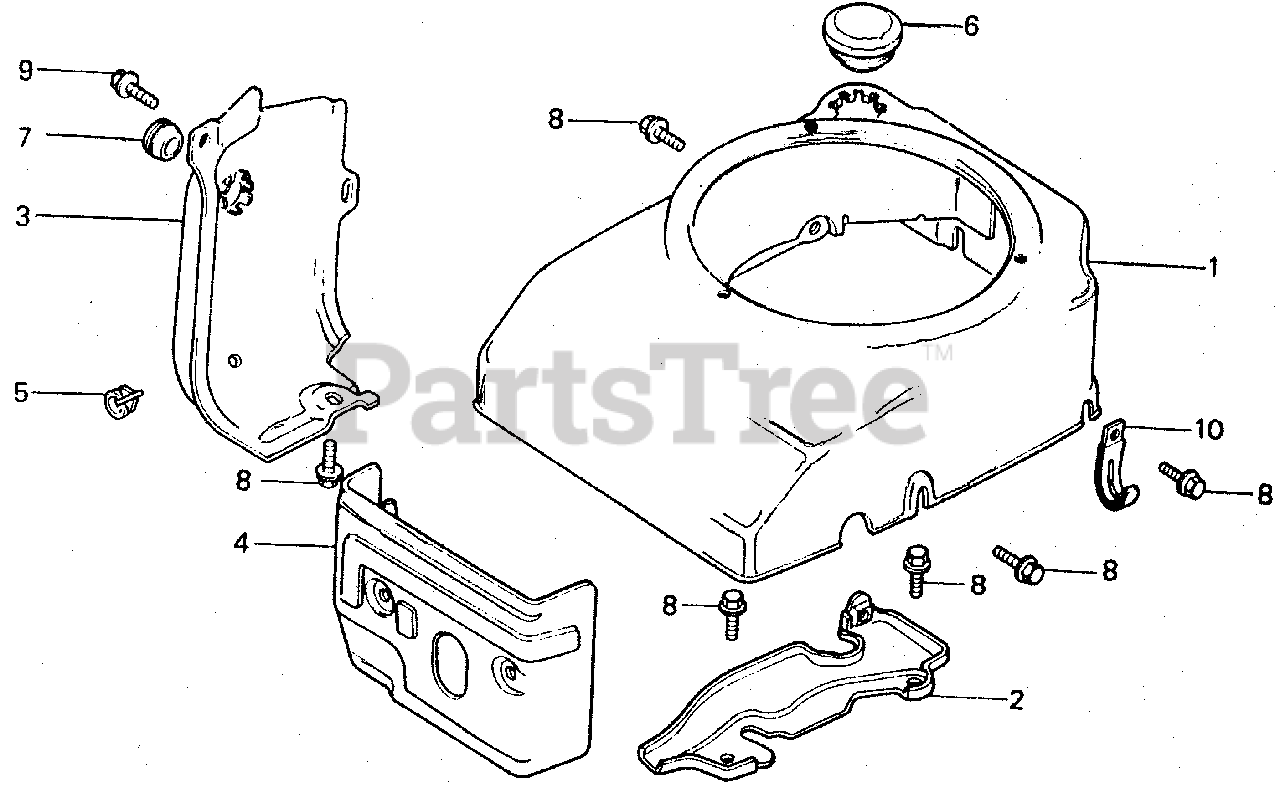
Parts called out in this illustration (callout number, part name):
1	COVER, FAN *R8* (BRIGHT RED) (NOT AVAILABLE)
2	PLATE, SIDE
4	COVER, TOP (NOT AVAILABLE)
5	CLIP, IGNITION WIRE (8MM)
6	GROMMET B, SIDE PANEL
7	GROMMET, DRAIN HOLE
8	BOLT, FLANGE (6X12) (CT200)
9	BOLT, FLANGE (6X14) (CT200)
10	CLIP, WIRE
